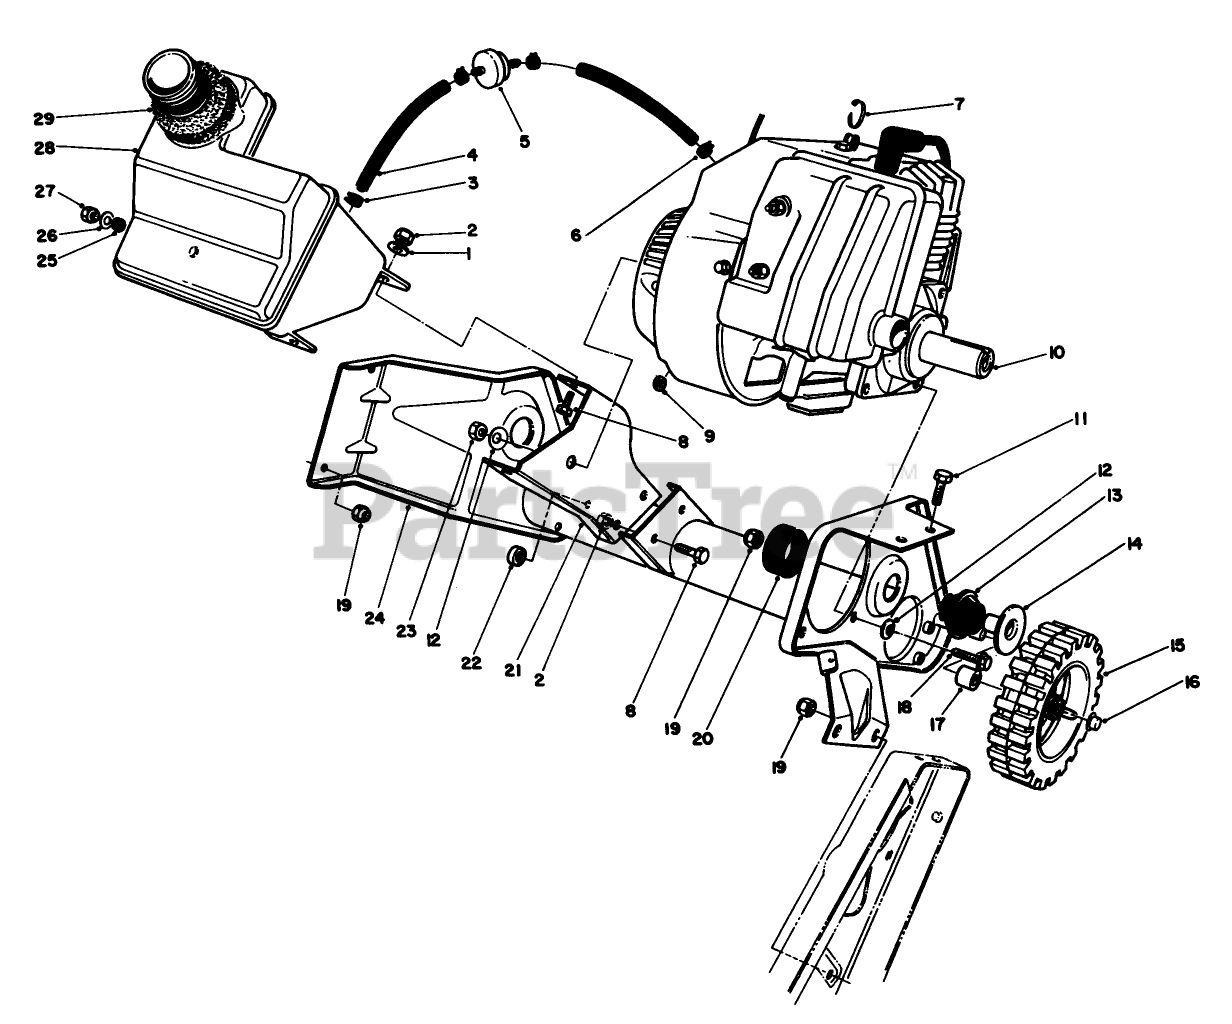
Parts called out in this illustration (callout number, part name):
1	WASHER-FLAT
2	NUT-LOCK, NI
3	Clamp
4	GAS LINE
5	FILTER-FUEL
6	CLAMP-HOSE
7	TIE-CABLE
8	SCREW-HH
9	SPACER-PLATE, PIVOT
10	Engine Assembly
11	SCREW-HH
12	WASHER-BELLEVILLE
13	MOUNT-REBOUND
14	SPACER TUBE
15	WHEEL
16	NUT-PUSH
17	SPACER-WHEEL
19	NUT-LOCK, NI
20	LOAD MOUNT
21	Support-Recoil
22	SPACER-WHEEL
23	NUT (F/W & PPP)
24	Wa-Frame
25	Grommet
26	WASHER-PLAIN
27	NUT-LOCK, CONE
28	Tank-Fuel (Incl. Ref. #25)
29	SEAL-FOAM
